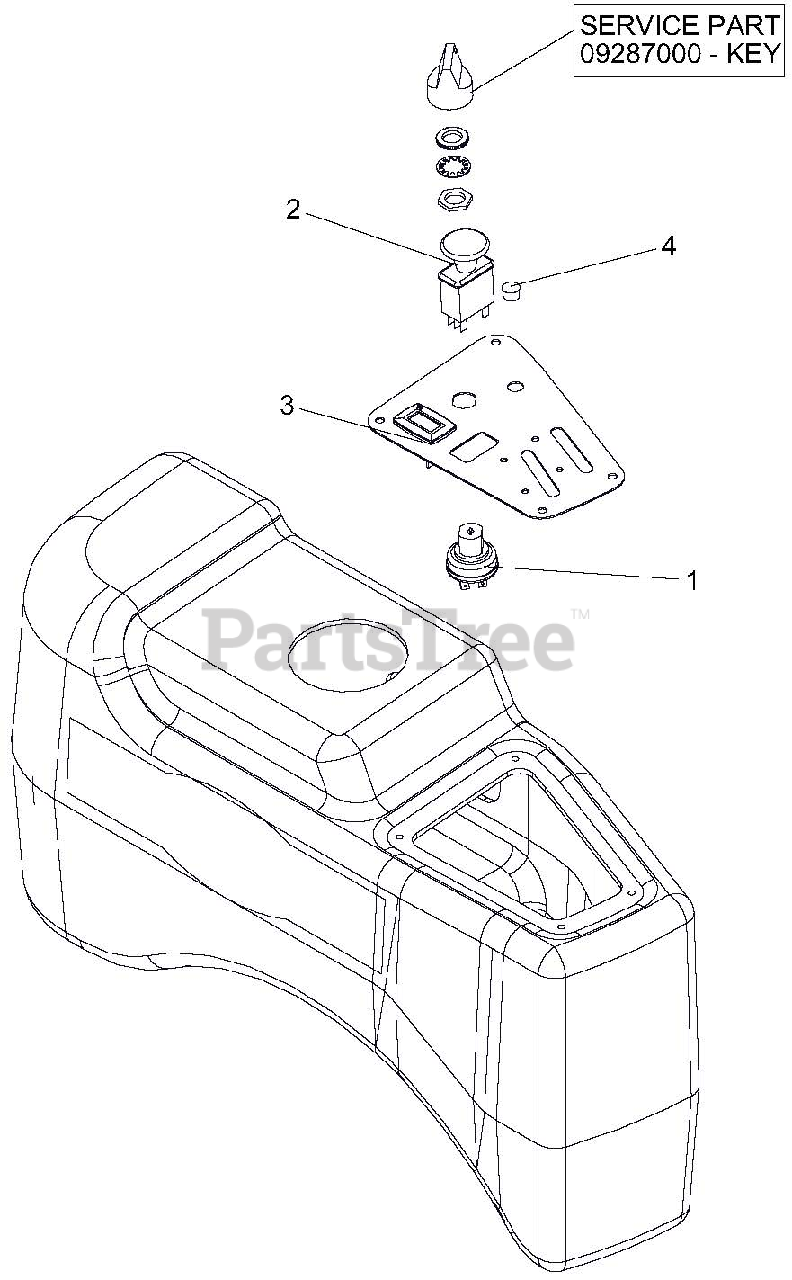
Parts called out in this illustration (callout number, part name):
1	SWITCH, IGNITION
2	SWITCH, CLUTCH
3	METER, HOUR W/MAINTENANCE
4	PLUG, HOLE .50 DIA
5	KEY
